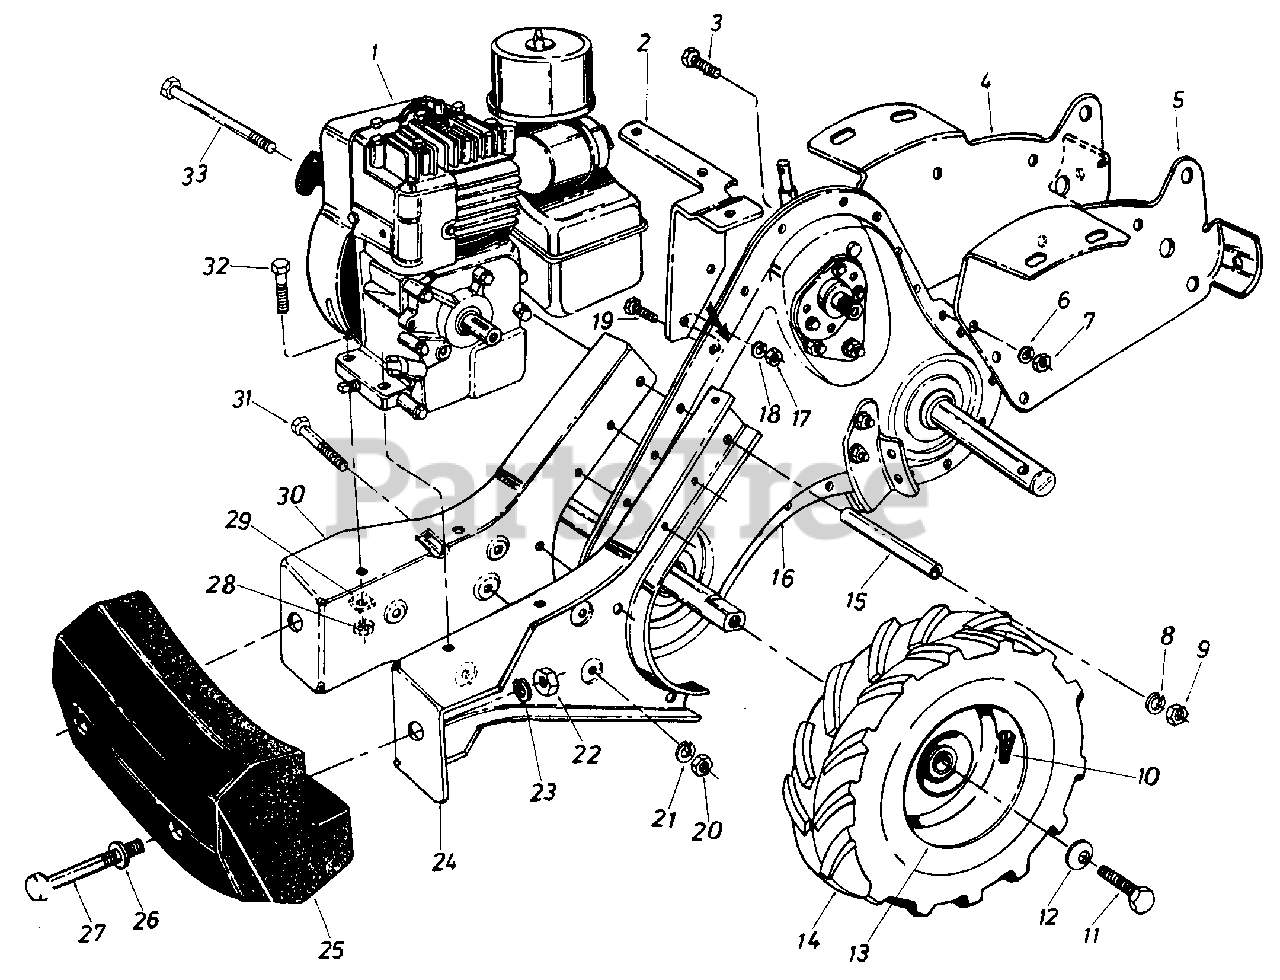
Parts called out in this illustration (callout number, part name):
1	Engine
2	Belt Cover Mounting Brkt.
3	Hex Bolt 3/8-16 x 1.00" Lg.*
4	Tine Shield Mtg. Brkt.-R.H.
7	Hex Nut 3/8-16 Thd.*
8	L-Wash. 5/16' I.D.*
9	Hex Nut 5/16-18" Thd.*
10	Air Valve
11	Hex Bolt 5/16-24 x .62" Lg.*
12	Bell-Wash. .345" I.D. x .88"
13	Wheel Rim Ass'y. Only
14	L.H. Wheel Ass'y. Comp.
14	R.H. Wheel Ass'y. Comp.
14	Tire Only 13 x 5.0
15	Spacer 3/8" I.D. x 3.38" Lg.
16	Transmission Comp.
17	Hex Nut 5/16-18 Thd.*
18	L-Wash. 5/16" I.D.*
19	Hex Bolt 5/16-18 x .75" Lg.*
20	Hex Nut 3/8-16 Thd.*
21	L-Wash. 3/8" I.D.-H.D.
22	Hex Nut 1/2-13 Thd.*
23	L-Wash. 1/2" I.D.*
26	Fl-Wash. .510" I.D. x 1.0"
27	Hex Bolt 1/2-13 X 5.00" Lg.*
28	Hex Nut 5/16-18 Thd.*
29	L-Wash. 5/16" I.D.*
32	Hex Bolt 5/16-18 x 1.50"*
33	Hex Bolt 5/16-18 x 4.75" Lg.Gr. 2
